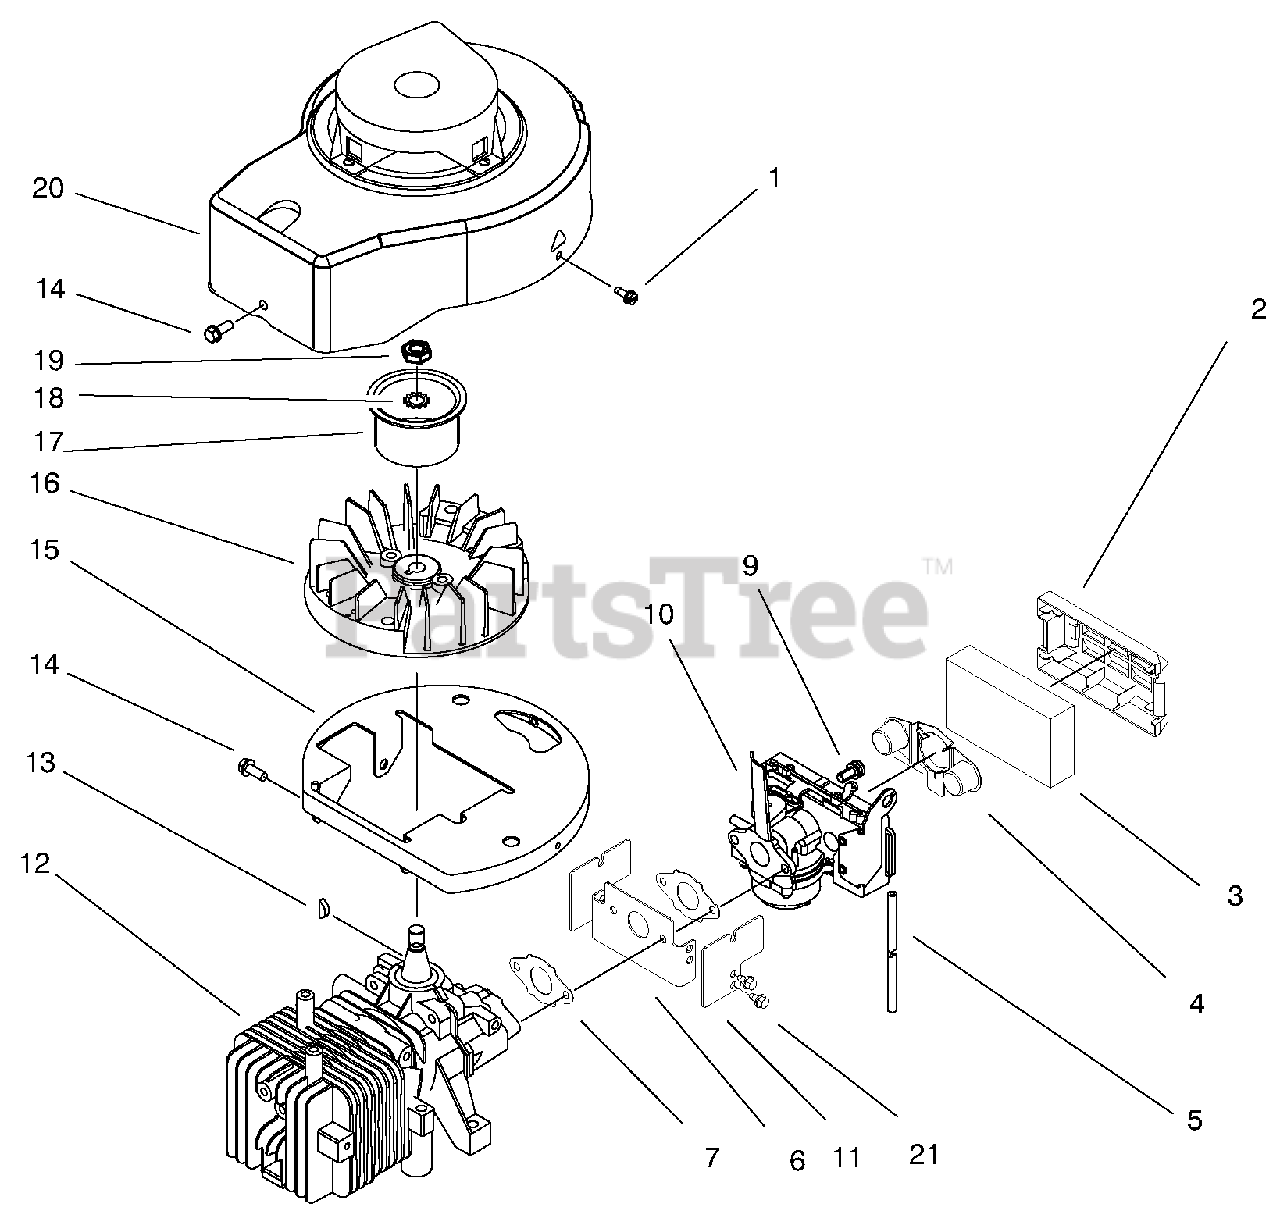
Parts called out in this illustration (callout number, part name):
1	SCREW VF
2	Cover-Air Filter
3	ELEMENT-AIR FIL VF
4	SHIELD-FUEL V
5	HOSE-PRIMER
6	SHIELD-CARB V INTL
7	GASKET-CARB VF
10	Carburetor Assembly
11	SHIELD- GOV. V INTL
12	SHORT BLOCK
14	SCREW
15	Base-Shroud
16	FLYWHEEL(MACH) V
17	HUB-STARTER V
18	WASHER-LOCK
20	SHROUD
21	SCREW V
